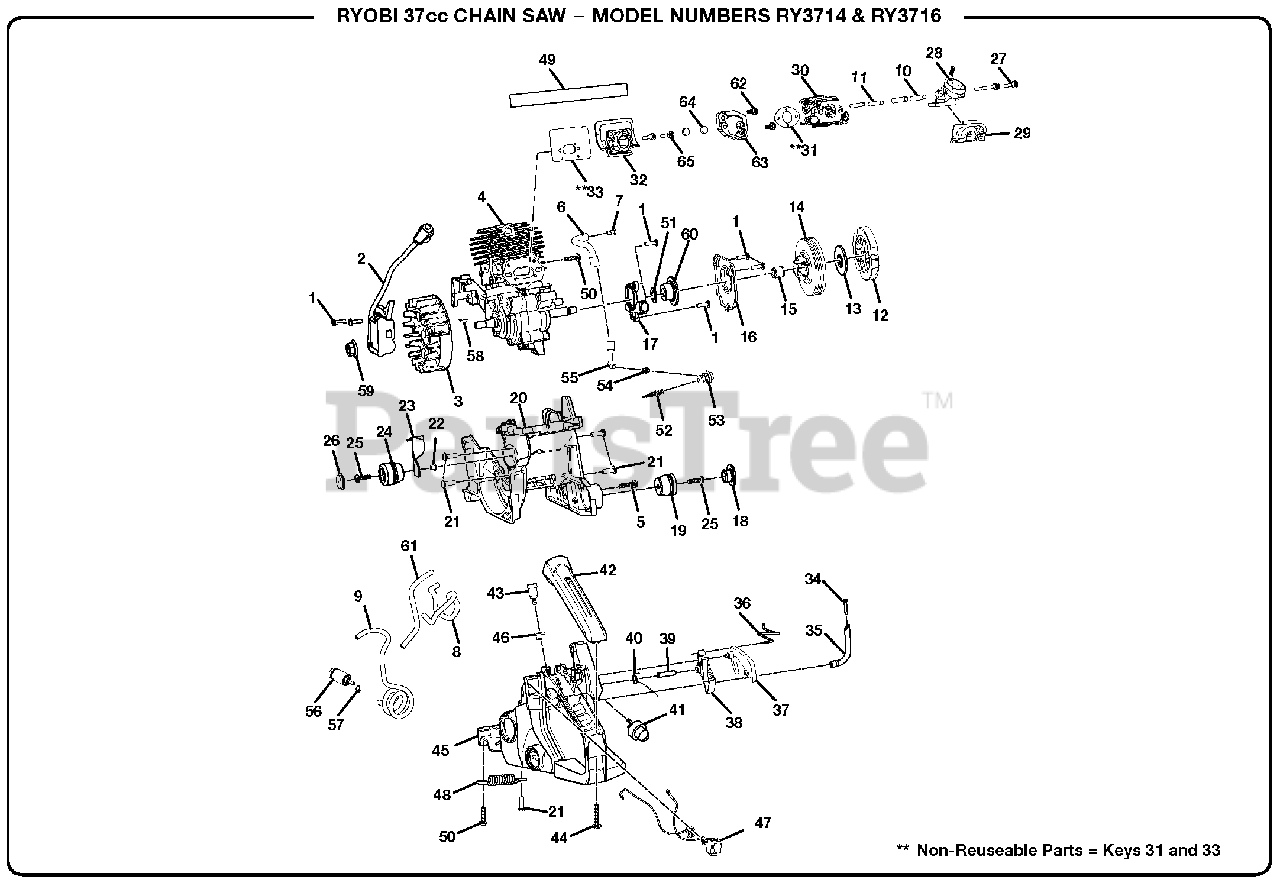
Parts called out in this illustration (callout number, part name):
1	Screw (M4 x 14 mm, T20 Torx Hd.)
2	Ignition Assembly
3	Flywheel Assembly
4	Short Block
5	Screw (M5 x 19 mm, T25 Torx Hd.)
6	Hose (Oil Pump Outlet)
7	Pin (Oil Pump Outlet)
8	Fuel Hose (Primer Bulb to Tank, 153 mm)
9	Fuel Hose
10	Fiberglass Sleeve
11	Plastic Tube (Carburetor Screw, 28 mm)
12	Clutch Assembly
13	Plate for Clutch Assembly
16	Oil Pump Cover
18	Damper Cap
20	Engine Case
21	Screw (M5 x 14 mm, T25 Torx Hd.)
25	Screw (M5 x 16 mm, T25 Torx Hd.)
26	Damper Cap.
27	Bolt (M4 x 45 mm, T25 Torx Hd. Carburetor)
28	Intake Manifold
29	Throttle Rod Grommet
30	Carburetor Assembly
31	Gasket
33	Heat Dam Gasket
35	Breather Pipe
36	Throttle Rod
37	Safety Rock Arm
38	Throttle Trigger
39	Spring Pin
40	Throttle Spring
41	Primer Assembly
42	Grip Cover
43	Breather Assembly
44	Screw (M5 x 27 mm, T25 Torx Hd.)
45	Rear Handle Assembly
46	Breather Grommet
47	Stop Switch Assembly
49	Foam Seal.
50	Screw (M5 x 19 mm, T25 Torx Hd.)
51	Washer (Oil Pump Drive Gear)
52	Cone Spring
55	Rubber Pipe In Oil Pump
56	Fuel Filter
57	Fuel Pipe Clip
58	Woodruff Key
59	Nut.
60	Oil Pump Drive Gear
61	Fuel Hose (Primer Bulb to Carburetor, 160 mm)
62	Screw (M5 x 13 mm, T25 Torx Hd.)
63	Intake Adapter (37cc)
65	Screw (M4 x 19 mm, T25 Torx Hd.)
